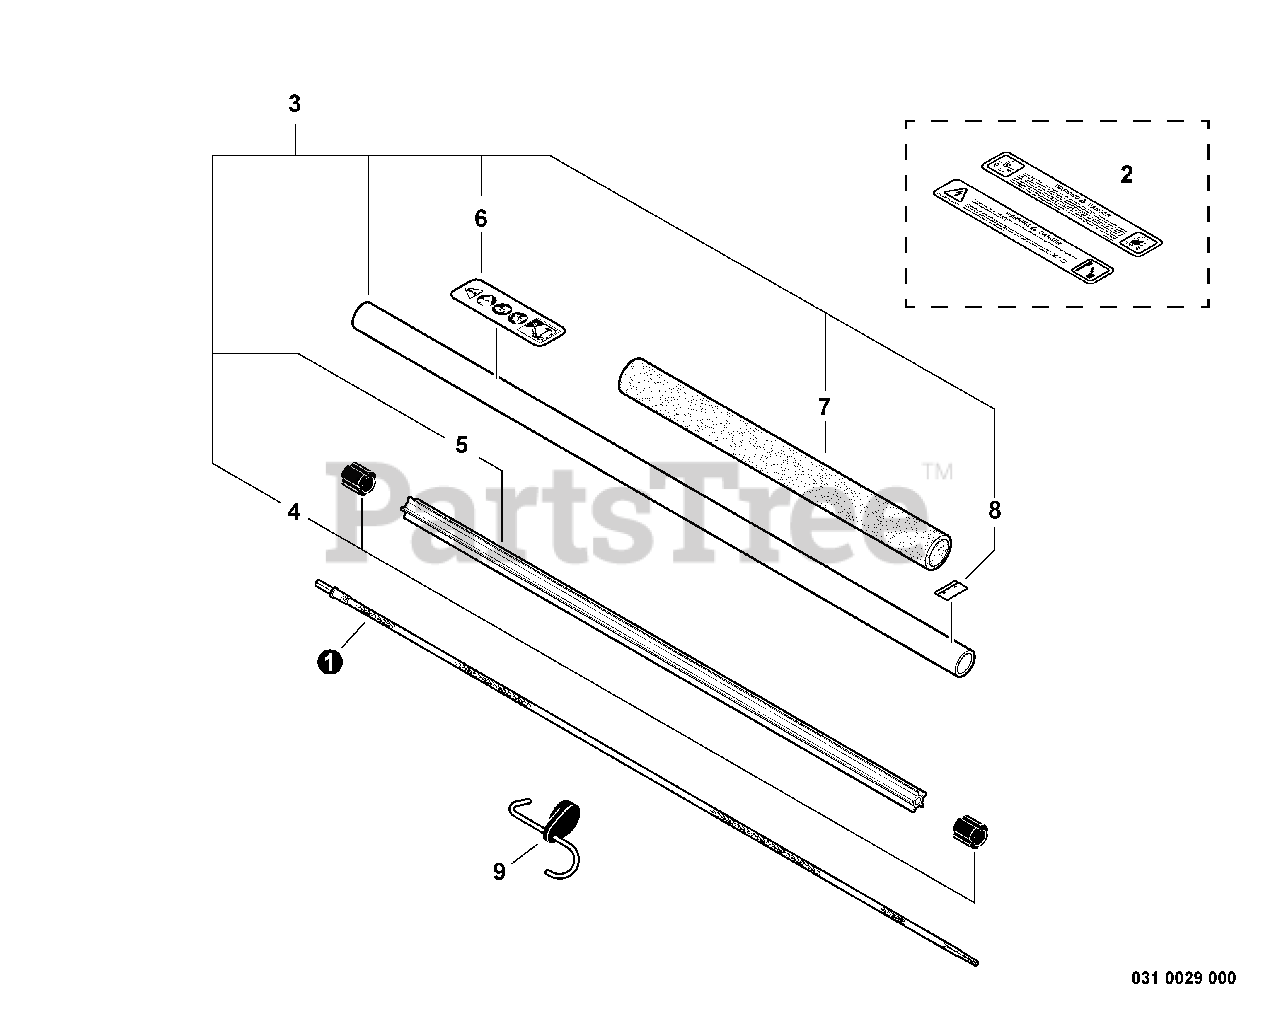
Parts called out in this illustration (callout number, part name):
1	DRIVESHAFT - FLEXIBLE
2	LABEL - CAUTION
3	MAIN PIPE ASSY
5	LINER - FLEXIBLE
6	LABEL - CAUTION
7	GRIP, HANDLE
8	LABEL - ALIGNMENT
9	PAS ATTACHMENT HANGER
